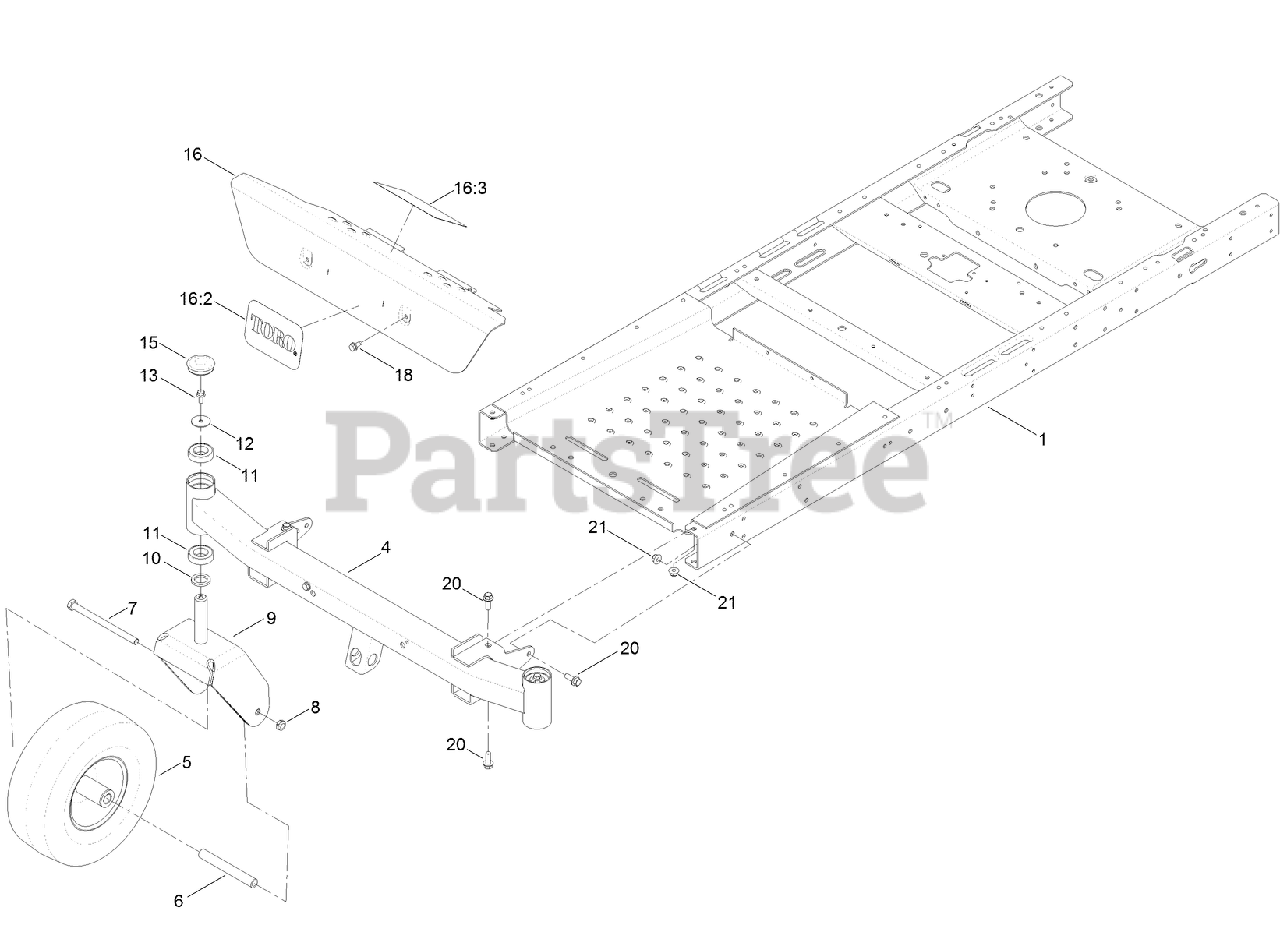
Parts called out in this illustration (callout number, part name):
1	FRAME ASM
4	AXLE ASM
5	13 INCH WHEEL AND TIRE ASM
6	SPANNER
7	SCREW-HH
8	NUT-HEX
9	FORK-CASTER
10	WASHER-THRUST
11	BEARING-BALL
12	WASHER-FLAT
13	SCREW-HHF
15	CAP-GREASE
16	FOOTREST ASM
16:2	DECAL
16:3	DECAL-DANGER
18	SCREW-HWHTF
20	SCREW-HHF
21	NUT-HF, NI
